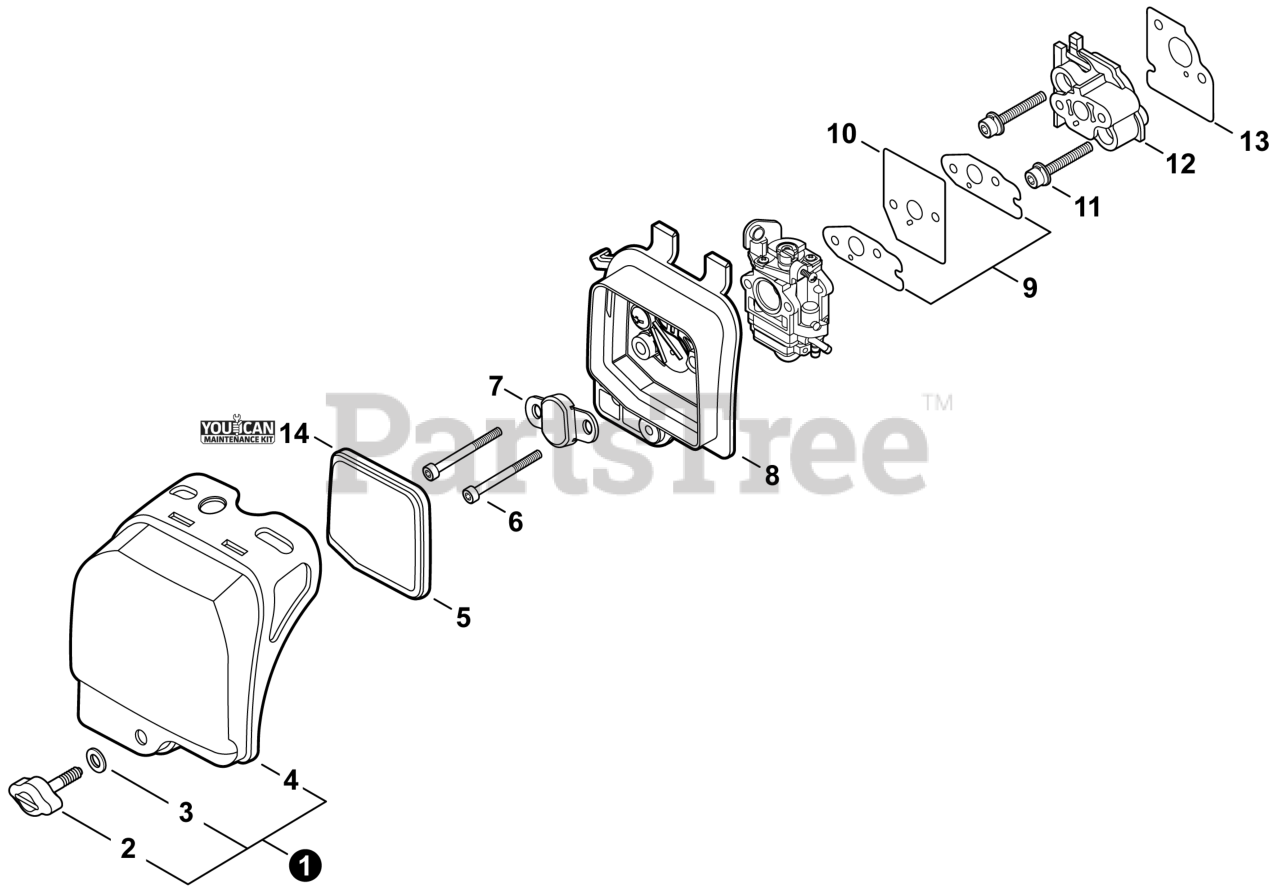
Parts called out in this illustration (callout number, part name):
1	COVER ASSY, AIR FILTER
2	THUMBSCREW
3	WASHER 5
4	COVER, AIR FILTER
5	FILTER, AIR
6	BOLT M5×60
7	BRACKET
8	CASE ASSY, AIR FILTER
9	GASKET, INTAKE
10	PLATE, INSULATOR
11	BOLT 5×30
12	INSULATOR, INTAKE
13	HEAT SHIELD, INTAKE
14	TUNE-UP KIT - YOUCANT
